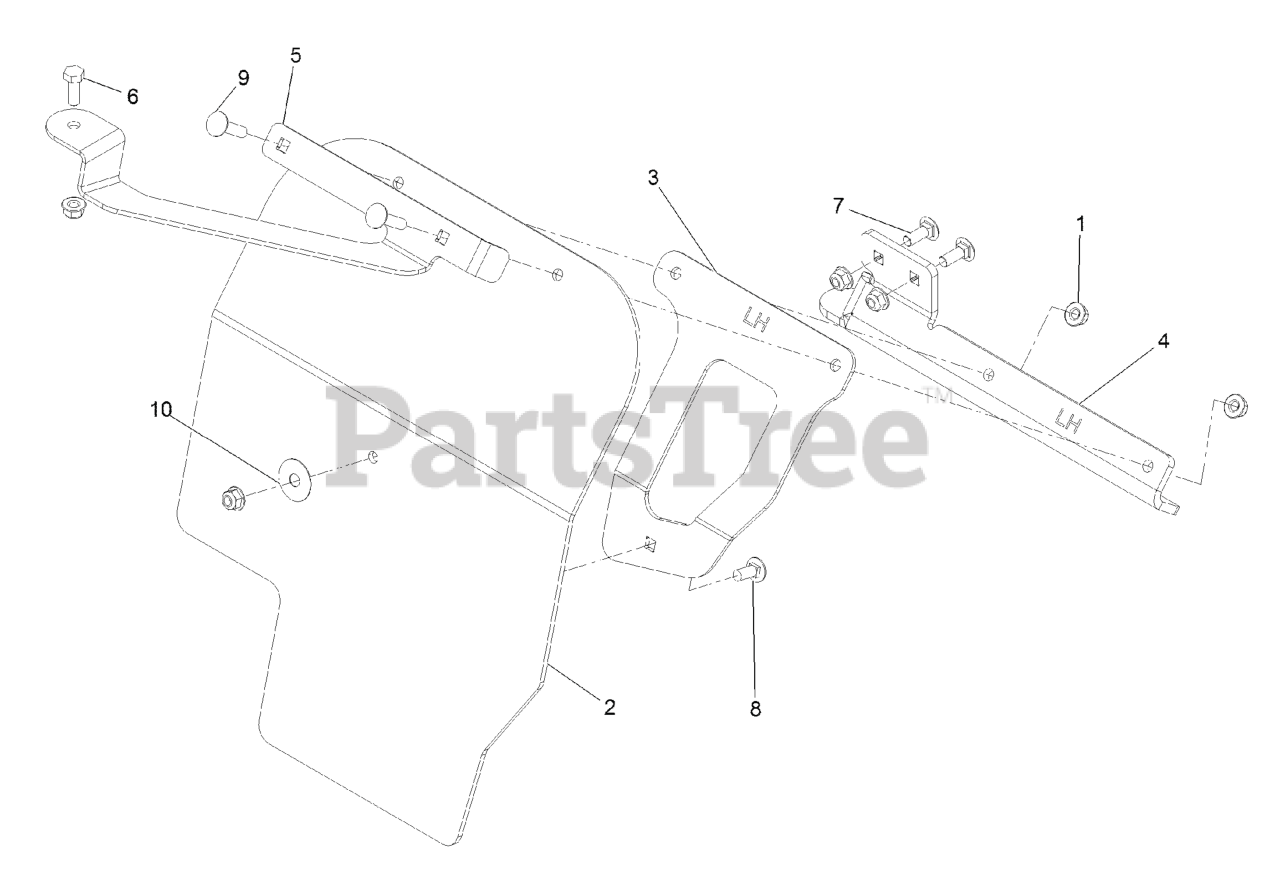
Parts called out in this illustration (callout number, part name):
1	NUT-HF, NI
2	LH MUD FLAP
3	SUPPORT, LH MUD FLAP
6	SCREW-HH
7	SCREW-CARR
8	SCREW-CARR
9	Bolt-Carriage 5/16-18 X 1 1/4
10	WASHER-PLAIN
